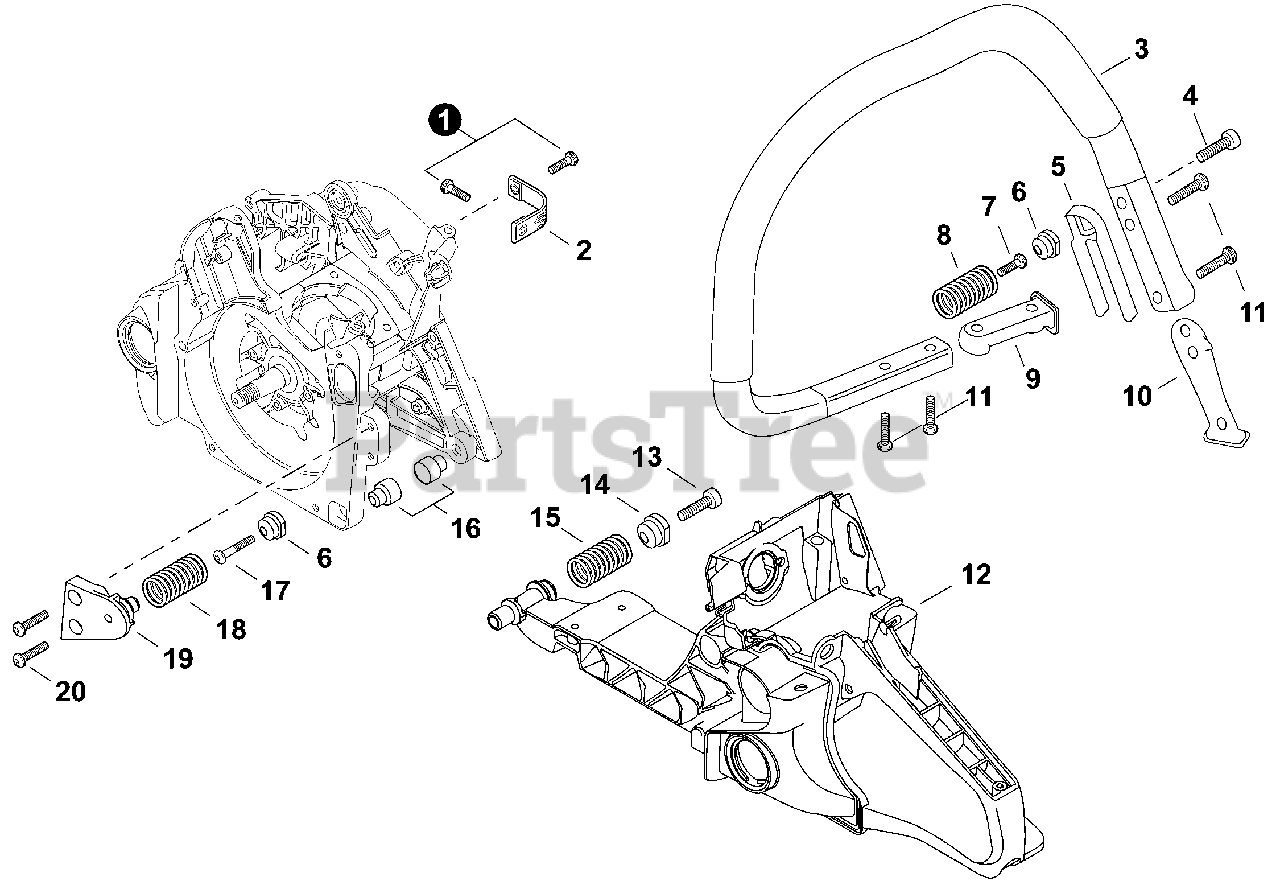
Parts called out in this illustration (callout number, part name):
1	BOLT, TORX 5×16
2	STRAP, SAFETY
3	HANDLE, FRONT
4	BOLT, TORX 6×20
5	HOLDER, SPRING
6	HOLDER, SPRING 14.4
7	BOLT, TORX 5×16
8	SPRING, COMPRESSION 17×38.4×2.6
9	MOUNT, HANDLE
10	MOUNT, HANDLE
11	BOLT, TORX 5×20
12	HANDLE, REAR
13	BOLT, TORX 6×20
14	HOLDER, SPRING 17
15	SPRING, COMPRESSION 20×40×3.3
16	CUSHION
17	BOLT, TORX 5×25
18	SPRING, COMPRESSION 17×36.7×2.6
19	HOLDER, SPRING
20	BOLT, TORX 5×20
